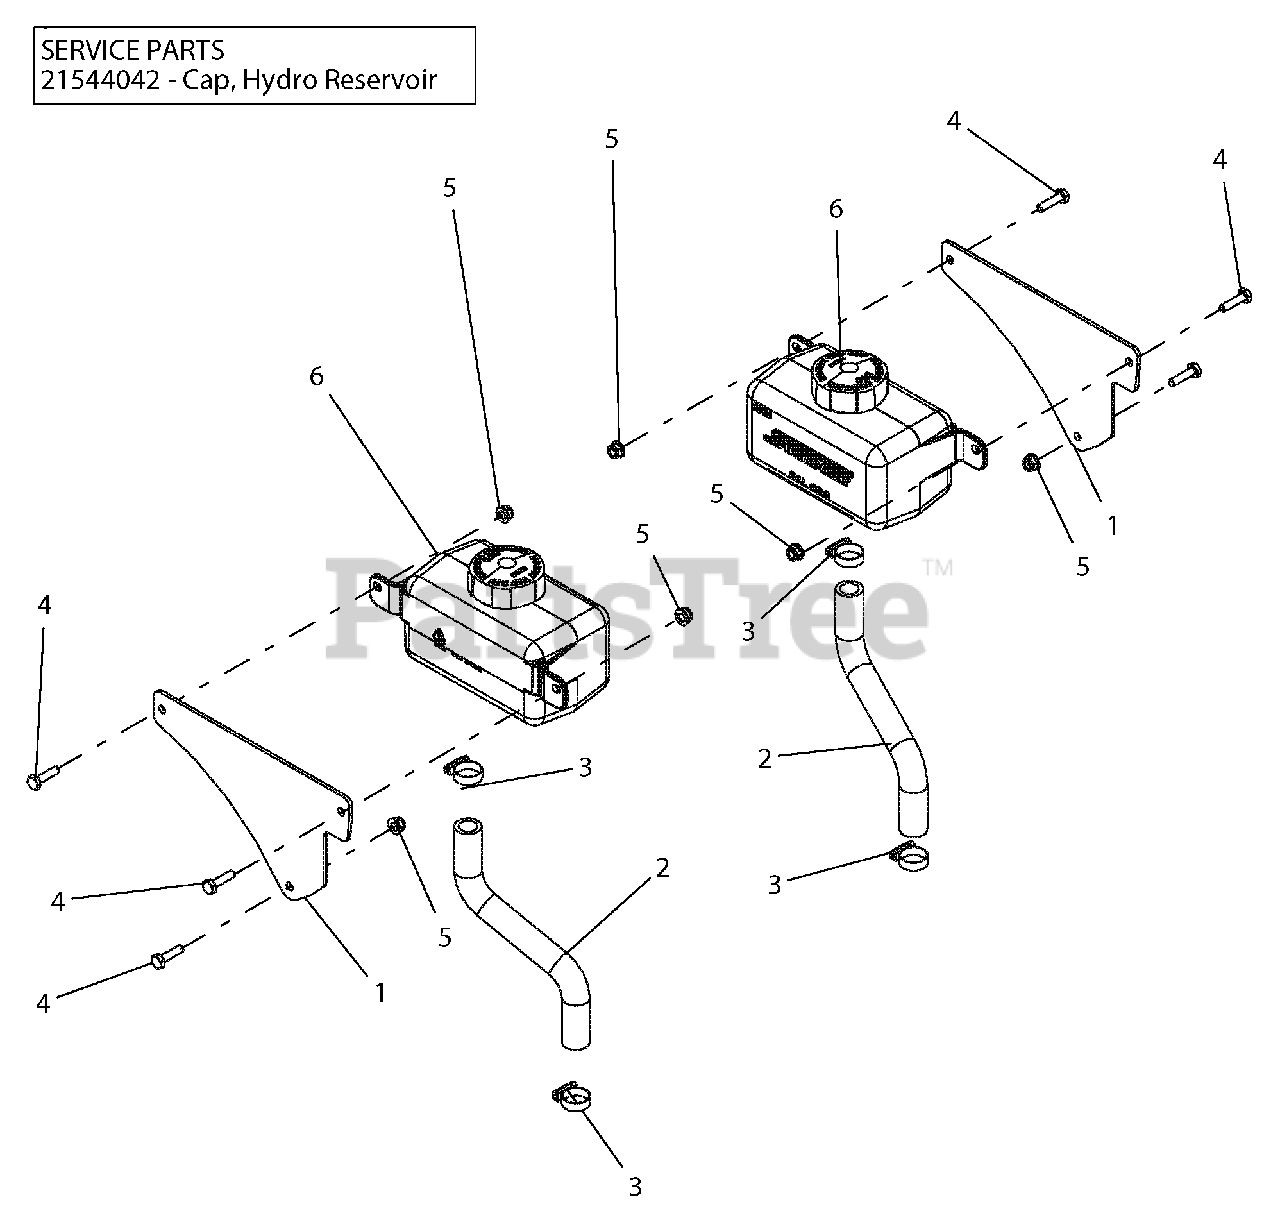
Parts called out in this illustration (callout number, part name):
1	PLATE, HYDRO OVERFLOW TANK MTG
2	HOSE, HYDRO OVERFLOW
3	CLAMP, .88 DIA HOSE
4	BLT-HEX .25-20X1.00 GR5 YWZC
5	NUT-LK-NYL-FLG .25-20 YWZC
6	TANK, HYD 1000ML
